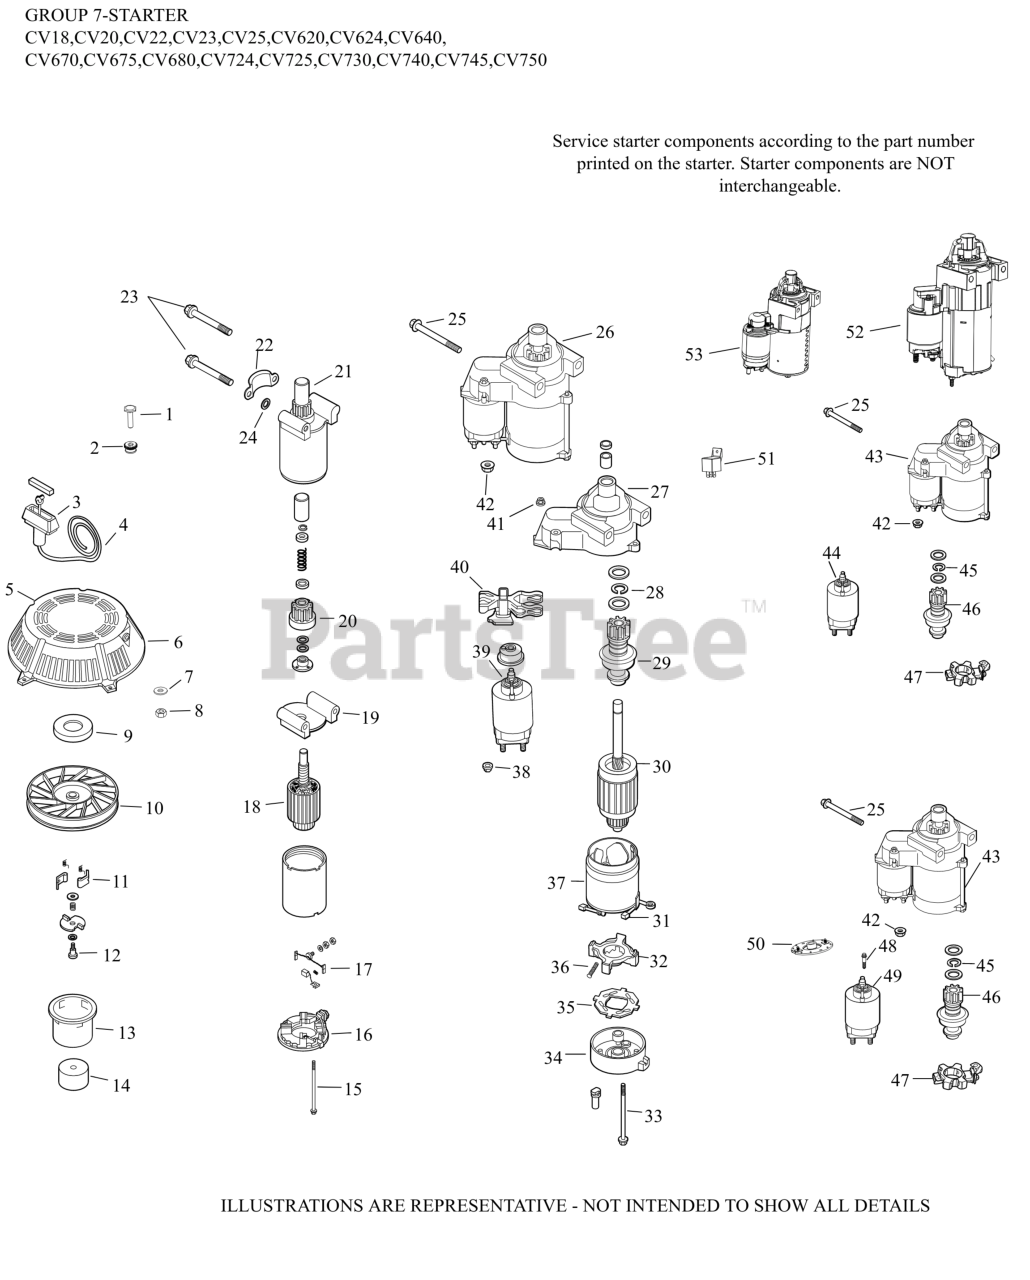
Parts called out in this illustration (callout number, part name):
25	SCREW, FLG M8X1.25X80
39	SOLENOID, ASSEMBLY-USE 25 435 06-S
42	NUT, FLG M8X1.25
43	STARTER, SOLENOID SHIFT-USE 25 098 11-S
43	STARTER,SOLENOID SHIFT-USE 25 098 11-S
43	ELECTRIC STARTER-USE 25 098 20-S
44	SOLENOID-(#DSC)
45	RING, RETAINING-(#DSC)
46	KIT, STARTER PINION
47	KIT, BRUSH HOLDER
48	SCREW, EXTERNAL TORX HEAD
49	KIT, SOLENOID
